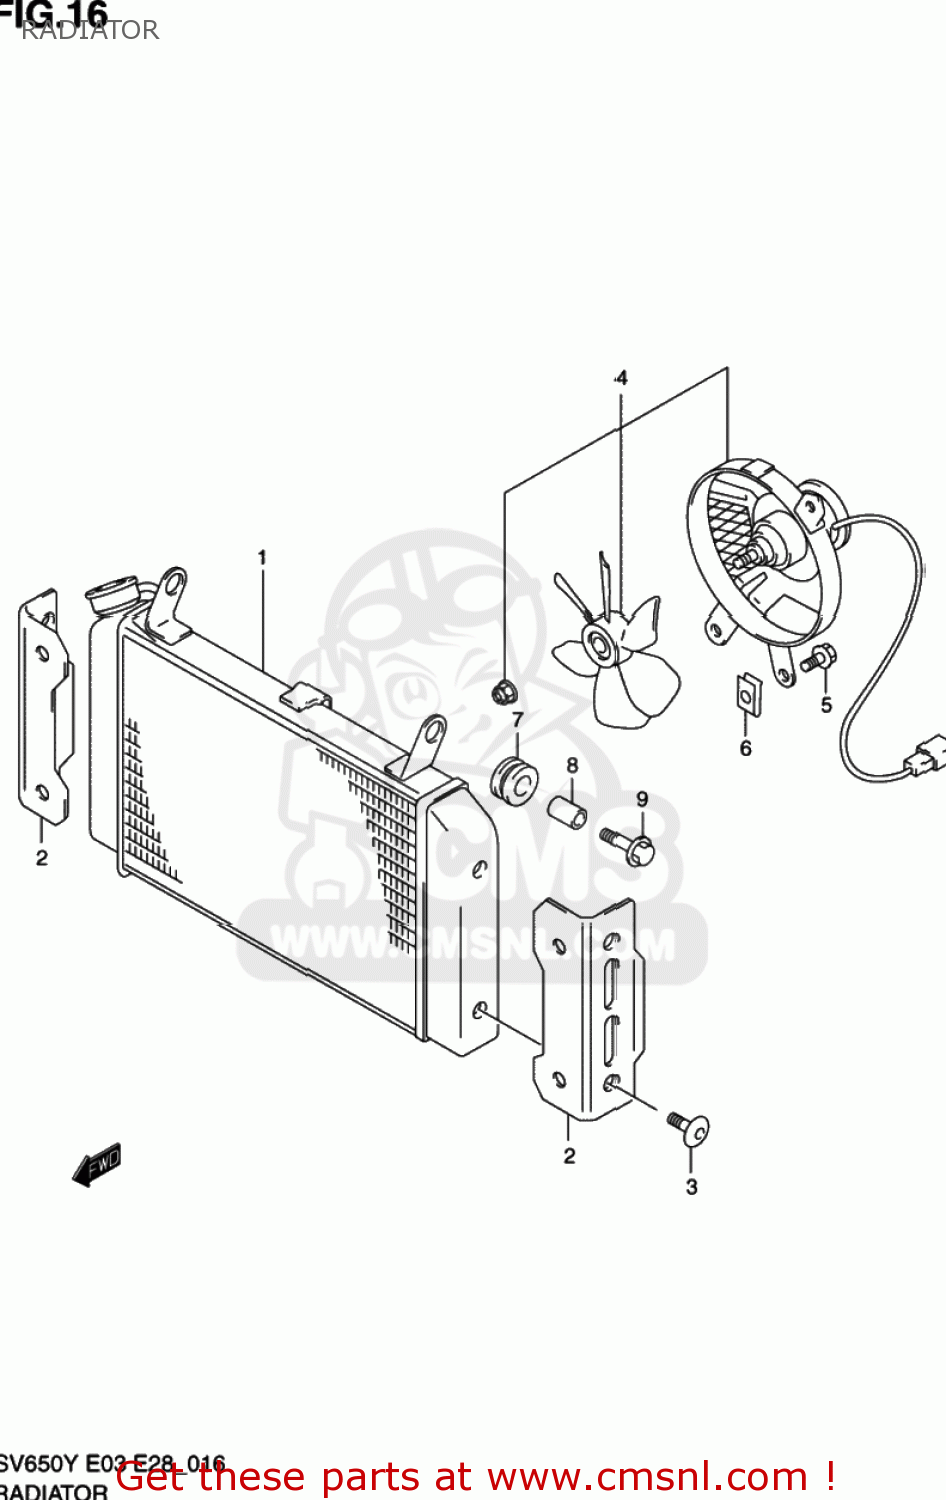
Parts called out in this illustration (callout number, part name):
1	RADIATOR ASSY,WATER
2	COVER,RADIATOR
3	SCREW(6X12)
4	FAN ASSY,RADIATOR
5	BOLT
6	NUT
7	CUSHION
8	SPACER(6.5X10X12)
9	BOLT(6X25)
